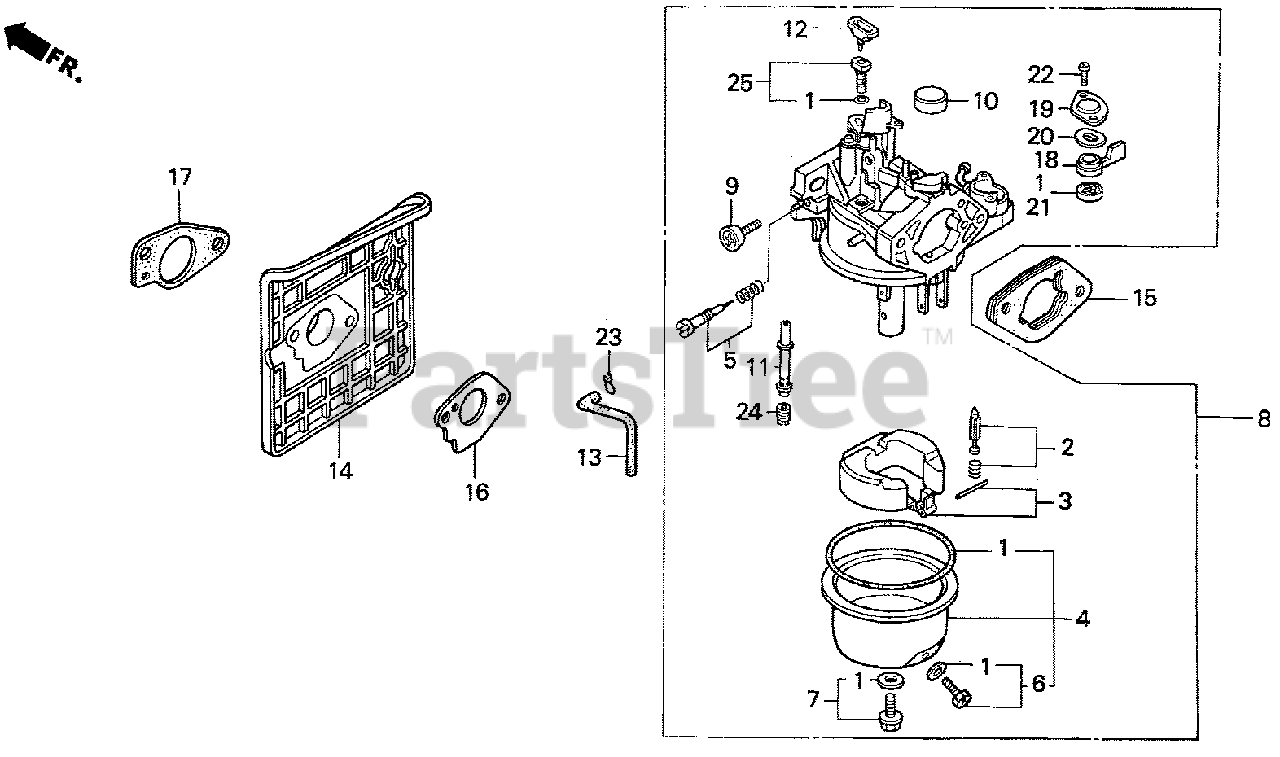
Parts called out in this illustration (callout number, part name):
1	GASKET SET
2	VALVE SET, FLOAT
3	FLOAT SET
4	CHAMBER SET, FLOAT
5	SCREW SET, PILOT
7	SCREW SET B
8	CARBURETOR ASSY.
9	SCREW, THROTTLE STOP
10	CAP, CHOKE LEVER DUST
11	NOZZLE, MAIN
13	TUBE, AIR VENT (75MM)
14	INSULATOR, CARBURETOR
15	SPACER, CARBURETOR
16	GASKET, CARBURETOR (Honda Code 2107894). (NOT AVAILABLE)
16	GASKET, CARBURETOR
17	GASKET, INSULATOR (Honda Code 2271385). (NOT AVAILABLE)
17	GASKET, INSULATOR
18	LEVER, VALVE
19	PLATE, LEVER SETTING
20	SPRING, VALVE LEVER
21	GASKET, VALVE
22	SCREW, PAN (3X6)
22	SCREW, PAN (3X8)
23	CLIP, TUBE (B8)
24	JET, MAIN (#82)
24	JET, MAIN (#85)
24	JET, MAIN (#88)
25	JET SET, PILOT (#40)
